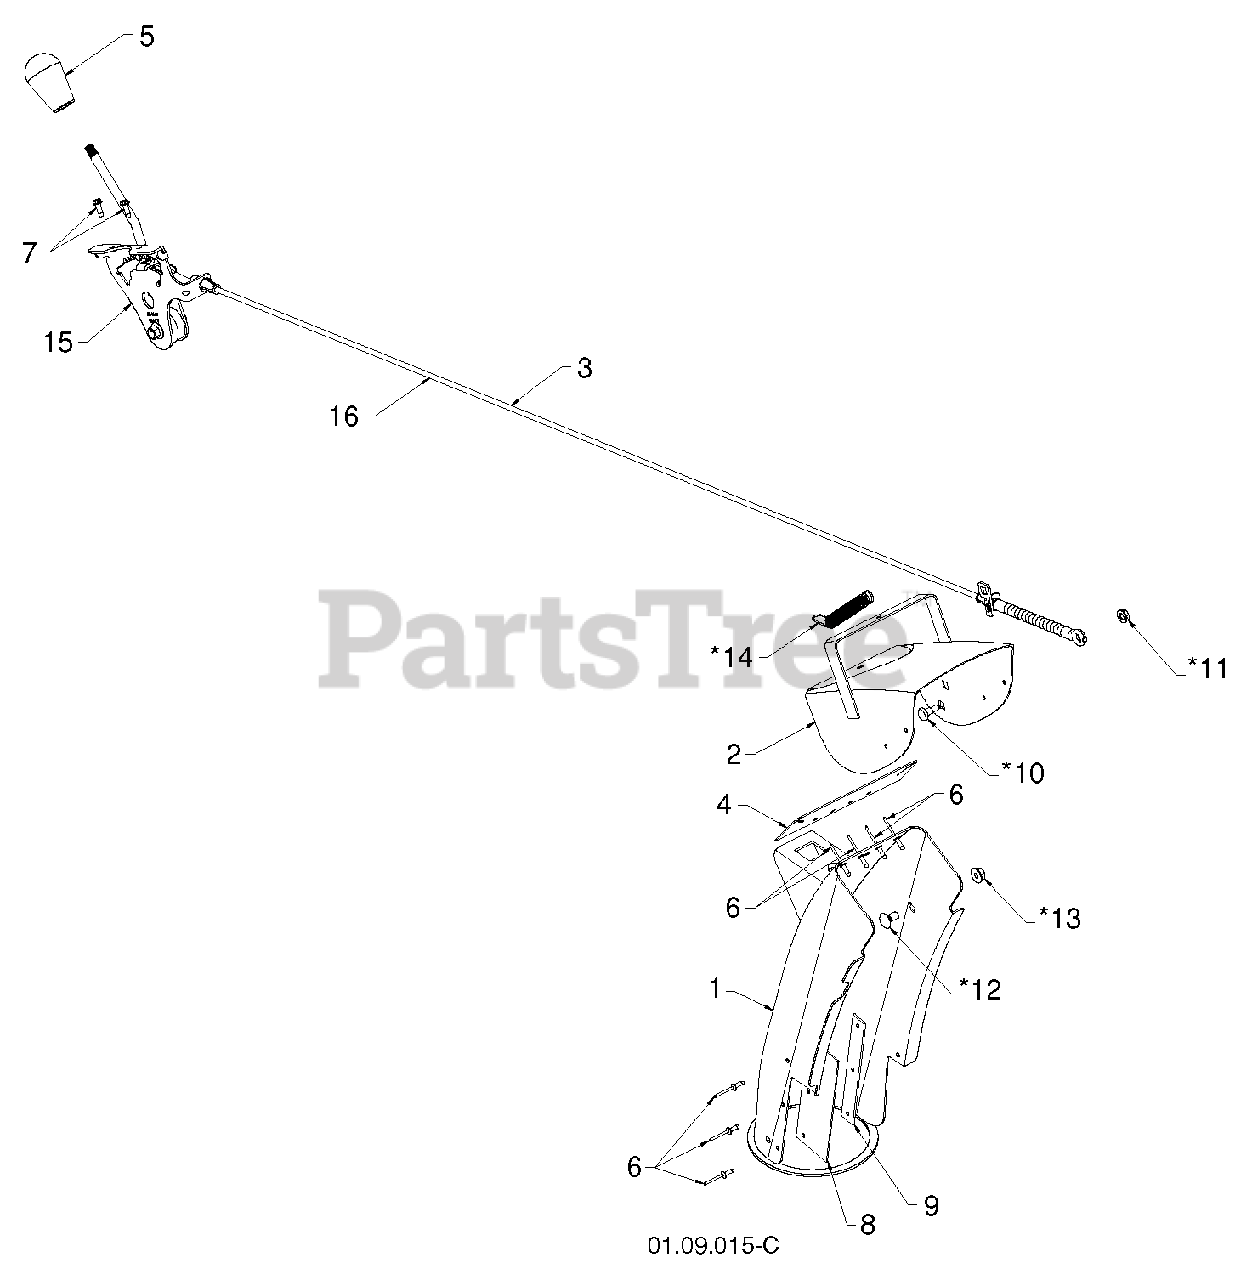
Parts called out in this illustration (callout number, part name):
1	RP_CHUTE.WELDMENT.SNOW.ORANGE
2	DEFLECTOR.WELDMENT.PNT.ORANGE
3	RP.CONTROL.ASM.DEFLECTOR.SNOW
4	SEAL.DEFLECTOR
5	KNOB LEVER, BLACK
6	RIVET BLIND
7	SCREW #10-24 X 5/8
8	SHIELD.SNOW.CHUTE
9	STRAP.SHEILD.RETAINER
10	BOLT, SHOULDER
11	NUT.HEX.FLANGE.1/4
12	BOLT
13	NUT.LOCK.5/16-18
14	SPRING.DEFLECTOR.REM.CHUTE
15	RP CNTRL.HEAD.ASSEM.DEFLECTOR
16	RB SERVICE.CHUTE.DEF.CBL.BLK
